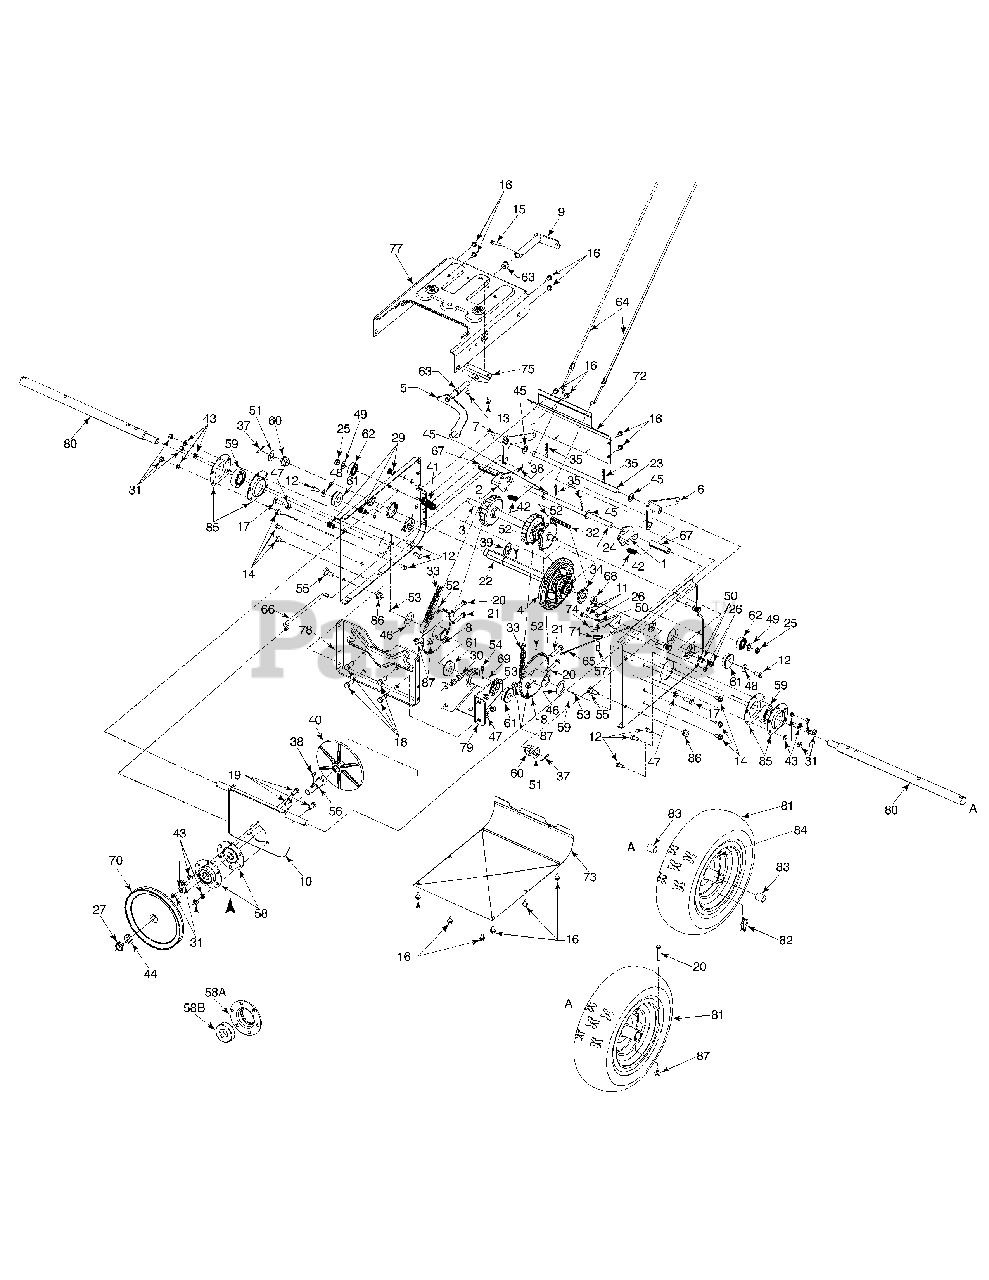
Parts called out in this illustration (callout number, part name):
1	LH Dog Assembly
2	RH Dog Assembly
3	Steering Shaft Assembly
5	Shift Ass’y Rod
6	Actuator Auger Bracket Ass’y
12	Hex L-Bolt 5/16-18 x .62
13	Hex Wash S-Tapp Scr 1/4-20 x .50
14	Hex Wash Hd Tap Scr. 5/16-18 x .75
15	Hex Bolt 1/4-20 x 1.00
16	Hex Wash Hd TT Scr. 1/4-20 x .625
17	Hex Hd. C-Sunk Scr. 3/8-16 x.880 Gr. 5
18	Hex Hd. C-Sunk Scr. 3/8-16 x .880 Gr. 5
19	Hex Bolt 5/16-18 x .75" Lg. Gr. 5
20	Hex Hd Cap Scr. 5/16-18 x 2.0 Gr. 5
21	Hex Screw 5/16-18 x 1.75" Lg.
22	Hex Drive Shaft
23	Actuator Shaft
24	Actuator Drive Shaft
25	Hex Nut 3/8-24
26	Hex Nut 1/4-28
27	Hex Jam Locknut 5/8-18 Gr. 5 Nylon
29	Nut Insert 3/8-16 UNC
30	Hex Nut 3/8-16
31	Hex Nut 5/16-18 hd. (Gr. 5)
32	#41 Chain 1/2" pitch x 36 links- Endless
33	#420 Chain 1/2" pitch x 40 links-Endless
34	10T Sprocket #41 x .500
35	Internal Cotter Pin
36	Int. Cotter Pin 5/16 DIA
37	Cotter Pin 1/8 x 1.0
38	No. 61 Hi-Pro Key 3/16 x 5/8
39	E-ring .875 diam.
40	Aluminum Drive Plate
41	Idler Extension Spring
42	Extension Spring .47 OD x 2.03 Lg.
43	L-Wash 5/16 ID
44	Lockwasher 5/16 ID
45	Flat Washer .531 ID x .930 OD
46	Flat Washer 1.03 ID x 1.62 OD x .03
47	Lockwasher Heavy 3/8" ID
48	Cupped Washer .345 ID x .88 OD x .06
49	Flat Washer .385 ID x .87 OD x .06
50	L-Wash 1/4 ID
51	Flat Washer .64 ID x 1.24 OD x .06
52	Lubricant - LPS 2 Industrial Strength (purchase locally)
53	Grease:Arctic:EP NLGI 1-58F
54	Grease Fitting
55	Shld. Scr. .500 Dia. x .335" Lg.
56	Drive Plate Spindle
57	Hex Shld.Scr.1/4-28 x .375
58	Ball Bearing .787 ID x 1.85 OD x .56
58A	Bearing Hsg. Ass’y.
58B	Brg. Housing 1.85" ID
59	Self aligning brg. 1.0 ID
60	Hex Flange Bearing .630 ID
61	Ball Bearing w/snap ring
62	Ball Bearing .5625 ID x 1.3750 x .437
63	Flange Bushing .500 ID x .627 OD
64	Steering Cable
65	Auger Idler Cable
66	Drive Clutch Rod
67	Split Spacer 1/2 x 5/8 x 2.69
68	Spacer .625 ID x 1.0 OD x .23
69	Spacer .6725ID x 1.125OD x 2.485
70	1/2" “V" Pulley .625 ID x 7.50 OD
71	Cable Guide Roller
80	Axle.995 x 14.10" Lg (33")
80	Axle .995 x 12.6" Lg. (28")
80	Axle .995 x 20.4" Lg. (45")
81	Wheel Assembly - LH /RH (31AE9M6) 16.5 X 4.8 Snow Hog
81	Wheel Assembly - LH (31AE9P6) 16 x 6.5 x 8 X-Trac
81	Tire 16.5 X 6.5 x 8 X-Trac
81	Rim for 16.5 X 4.8 Snow Hog
81	Rim for 16.5 X 6.5 x 8 X-Trac
83	Bearing 1.0 ID x 1.127 OD x 1.00
84	Air Valve
85	Bearing Housing
86	Flange L-Nut 3/8-16 Gr. F Nylon
87	Flange L-Nut 5/16-18 Gr. F Nylon
